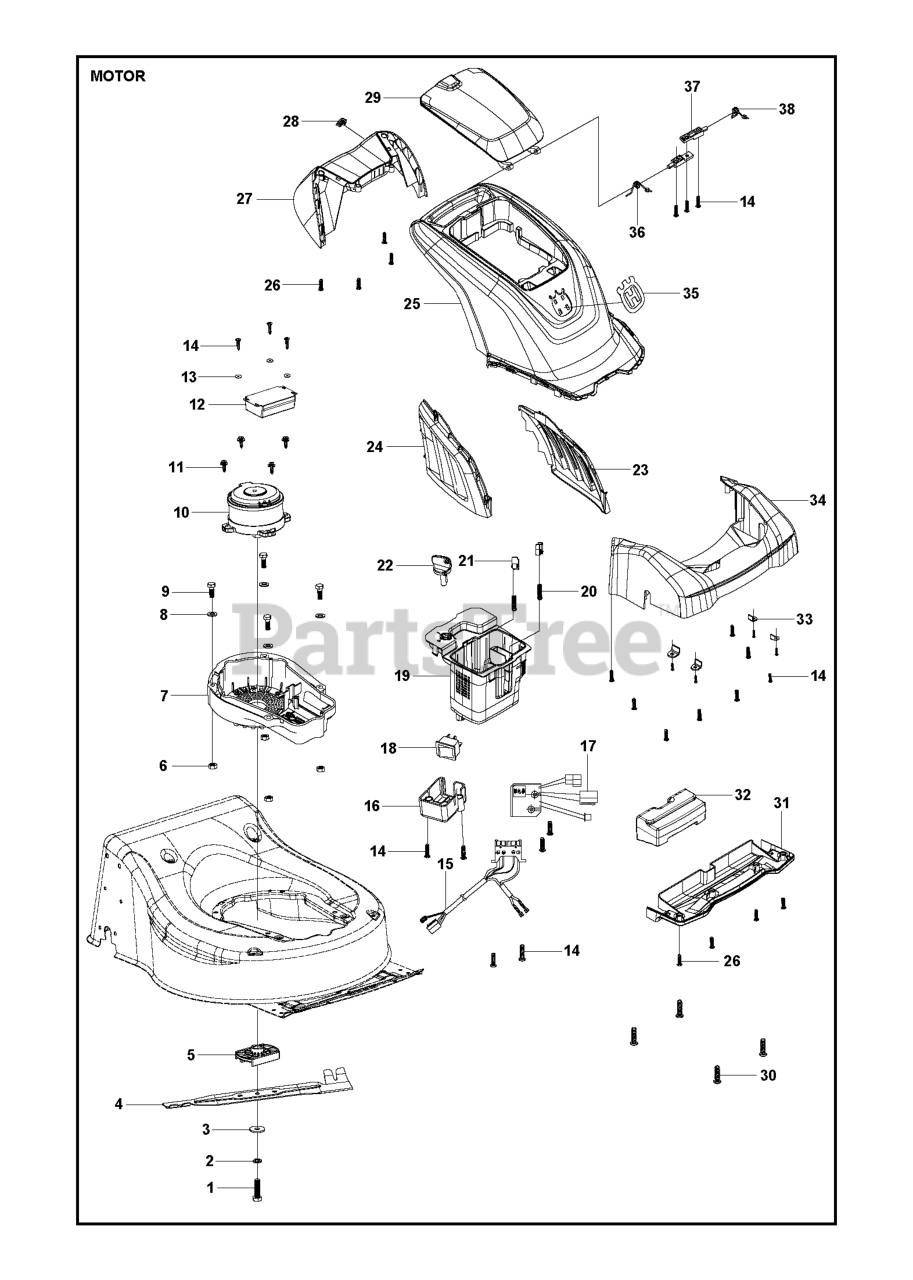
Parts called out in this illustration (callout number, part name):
2	SPRING WASHER
4	MOWER BLADE MULCH 40CM PRODUCT
5	BLADE SUPPORT
6	NUT LOCKING
15	WIRE BATTERY CONNECTOR
17	PRINTED CIRCUIT ASSY PUSH
18	KEY SWITCH
19	BOX BATTERY BOX
21	CAP COMPRESSION SPRING CAP
23	COVER LEFT AIR WINDOW PLATE
24	COVER RIGHT AIR WINDOW PLATE
25	COVER MOTOR COVER
27	COVER BACK COVER
29	COVER BATTERY LID
31	COVER FRONT HANDLE (UNDER SIDE
32	WEIGHT # 25100184101
34	COVER FRONT COVER
35	DECAL LOGO
36	TORSION SPRING
37	HINGE BATTERY LID HINGE
38	TORSION SPRING LEFT
